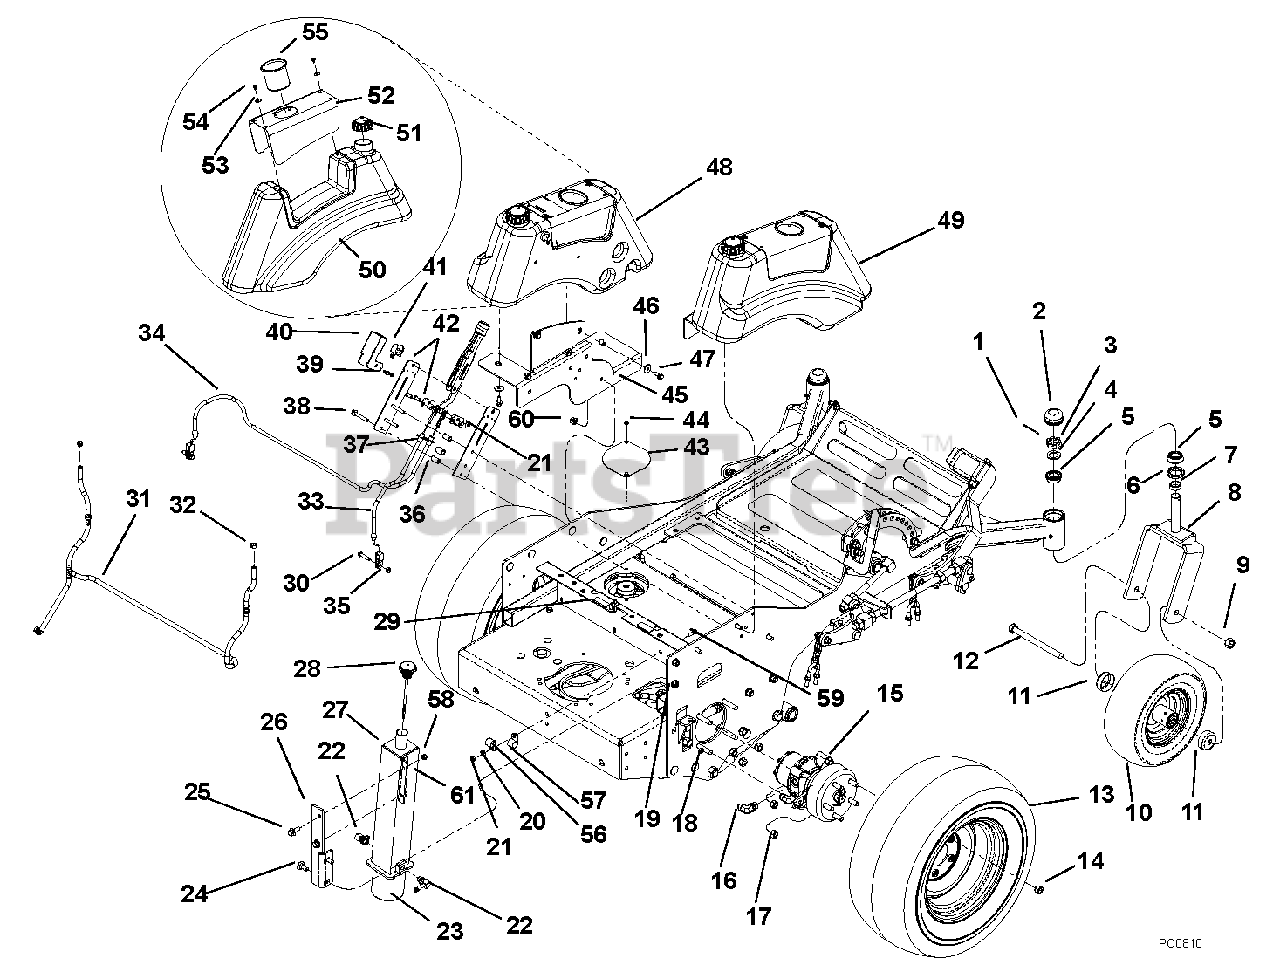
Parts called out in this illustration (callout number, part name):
1	PIN, COTTER, DIN94, 3.2 X 50-ST-ZN
2	2
2	CAP, DUST
3	NUT, 1-14 CASTLE Y
4	WASHER, JDS24-1.016 X 1.5X.134-ST
5	4
5	CONE, BEARING
6	SEAL, WHEEL BEARING
7	SPACER, CASTER
8	WLDT, YOKE CASTER
9	NUT, ISO4032, M16 X 2-10-ZN
10	ASSY, WHEEL & TIRE - CASTER
11	CAP, WHEEL
12	SCREW, HEX HEAD, METRIC
13	TIRE, ASSEMBLY 23 X 9.5-12 TURF
14	10
14	NUT, 1/2-20 LUG C
15	MOTOR, WHEEL RH W/ BRAKE
16	FITTING
17	LOCKNUT, 1/2-13 CENTER Y
18	SCREW, JDS19-0.500-13UNC-2AX2.5
19	LOCKNUT, FL, ISO7044, M10-1.50
20	LOCKNUT, 5/16-18 NYLOCK Y
21	WASHER, 5/16 X 3/4 FLAT
22	FTG, 90 9/16 MOR X 3/8 HOSE
23	FILTER, OIL
24	BOLT, RD HD SQ LO, NG NECK, METR
25	SCREW, HEX M10 X 1.5 X 25
26	BRACKET, RESERVOIR MOUNT
27	RESERVOIR, HYD. S/O
28	CAP, FILLER OIL
29	FOAM, 1/8" X 3/4" O.C. NEOPRENE
30	BOLT, M8-1.25 X 35 HEX HEAD 10
31	ASSY, FUEL LINE W/ CHECK VALVES
32	3
32	CLAMP, HOSE - 1/2" SPRING
33	CABLE, RH BRAKE
34	CABLE, LH BRAKE
35	4
35	NUT, M8 X 1.25 HEX GR8.8 Y
36	BUSHING
37	WLDT, RETAINER BRAKE
38	SCREW, HEX, FL, JDS121, M8 X 1.25 X 50
39	SCREW, SELFT, FL, JDS145, M5 X .8 X 12
40	WLDT, BRAKE SWITCH BRACKET
41	1
41	SWITCH, SEAT OVER RIDE (N.O.)
42	LEVER, BRAKE
43	PLATE, COVER
44	SCREW 5/16 X .500 HEX SELF TAPPING Y
45	BRACKET, LH TANK
46	8
46	WSHR-FL-STC .328 X1.00 X .094 YWZC REV
47	BLT-SERHFWH .312-18 X .750 YWZC REV
48	FUEL TANK ASSY, LH
49	FUEL TANK ASSY, RH
50	TANK, FUEL LH
51	CAP, FUEL
53	WASHER, FENDER .187 X .75
54	SCREW, MACHINE 10-24 X .375
55	CUPHOLDER
56	P-CLIP, .750 INSULATED
57	1
57	P-CLIP, .500 INSULATED
58	LOCKNUT, DIN6924, M10 X 1.5-10-ZN
59	BOLT, 5/16-18 X 1.00 HEX 5 Y
60	LOCKNUT, M8 X 1.25, FLANGED ZN
61	DECAL, HYDRO OIL SPECS
